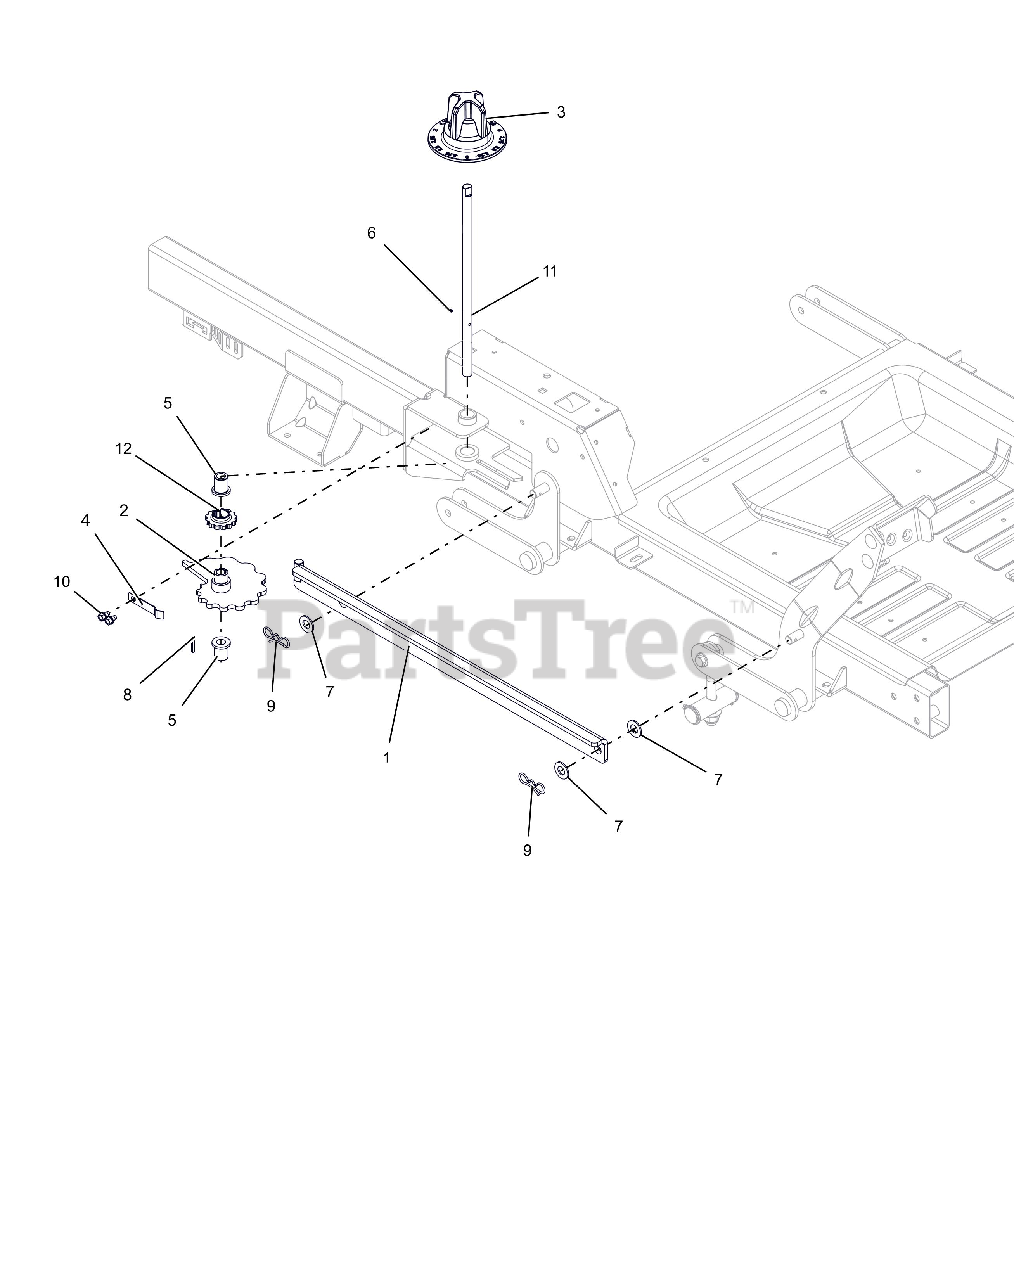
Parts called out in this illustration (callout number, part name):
1	WLDMT, HOC LINK
2	WLDMT, HOC CAM
3	KNOB, HOC DIAL
4	ARM, HOC DETENT
5	BSHG-FLG, .503X.750X.875X1.00
6	PIN-ROLL .125X1.00
7	WSHR-FL-NYL .518X1.000X.080
8	KEY, 1/8 X 1/8 X 1.0
9	PIN,BOW TIE LOCKING .091X1.875
10	@SCR-TAP .25-20X.37 HWH YWZ TR
11	SHAFT, HOC CAM IKON
12	GEAR, HOC INDEX
